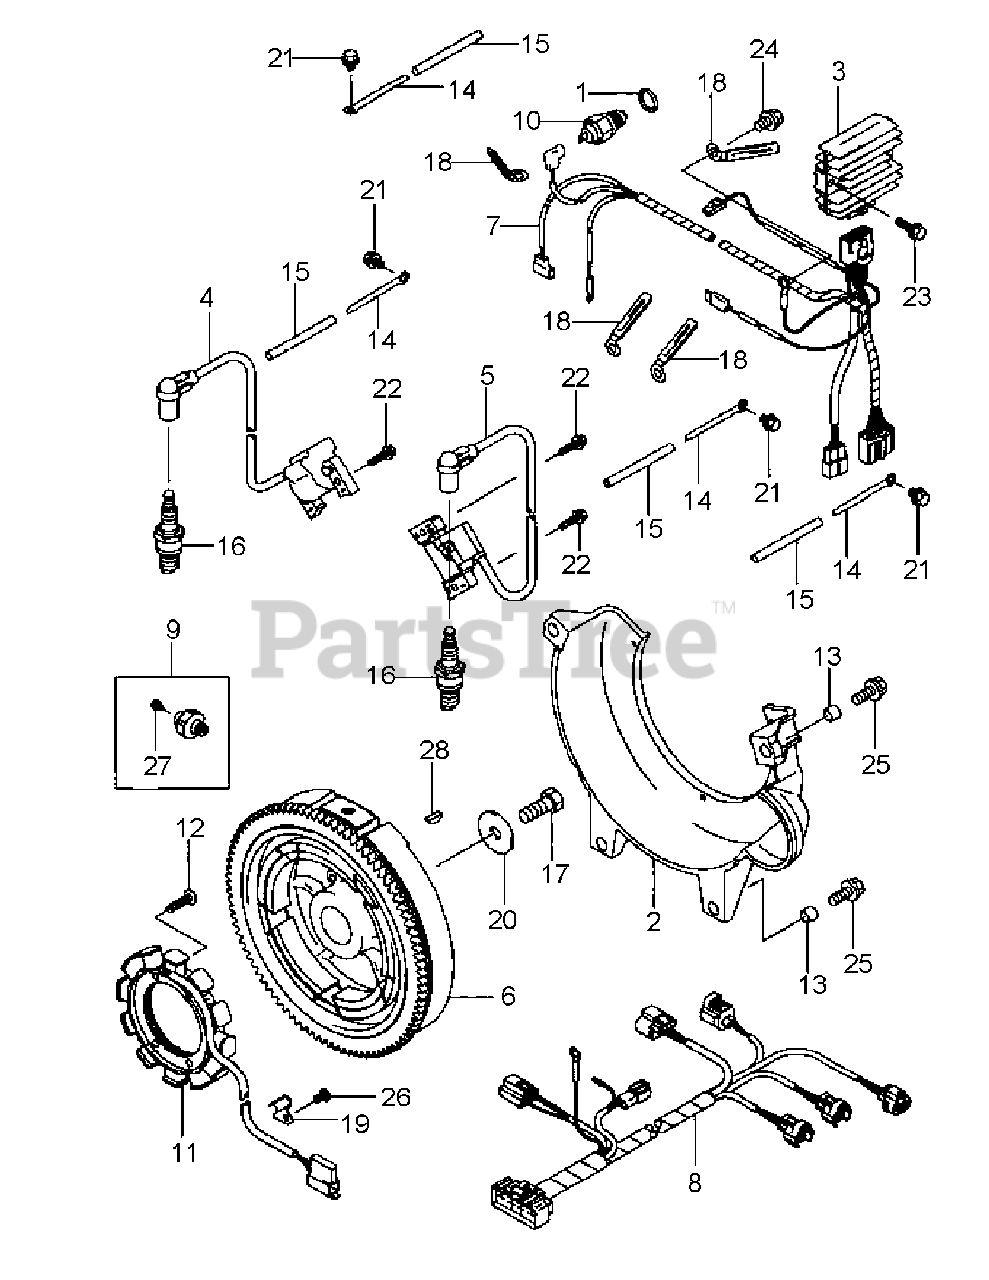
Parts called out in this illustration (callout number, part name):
2	FLYWHEEL COVER
3	VOLTAGE REGULATOR
4	IGNITION COIL #1
5	IGNITION COIL #2
6	FLYWHEEL
9	SWITCH
16	SPARK PLUG
21	FLANGED BOLT
22	FLANGED BOLT
23	FLANGED BOLT
24	FLANGED BOLT
25	FLANGED BOLT
28	WOODRUFF KEY
